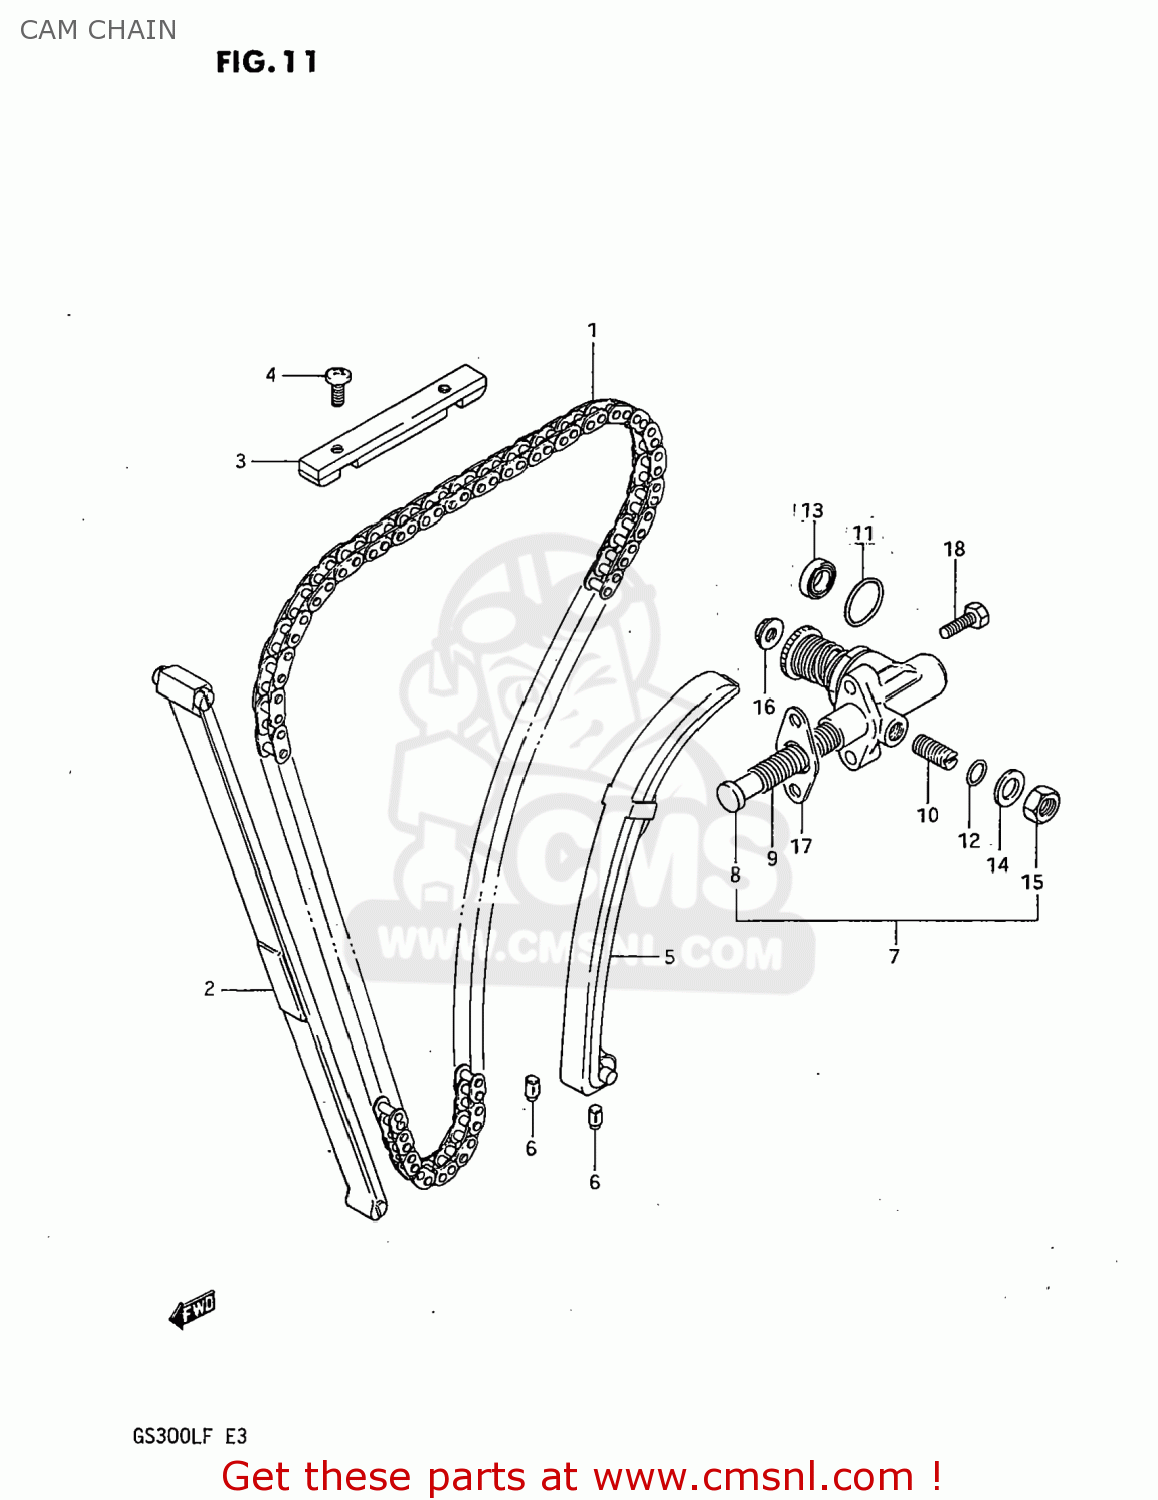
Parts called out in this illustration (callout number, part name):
1	CHAIN,CAMSHAFT DRIVE
2	GUIDE,CAM CHAIN NO.1
3	GUIDE,CAM CHAIN NO.3
4	SCREW
5	TENSIONER,CAM CHAIN
6	CUSHION,CAM CHAIN TENSIONER
7	ADJUSTER ASSEMBLY,TENSIONER
8	ROD,PUSH
9	SPRING
10	SCREW,TENSIONER ADJUST
11	O RING(D:2.4,ID:20.8)
12	O RING(D:1.9,ID:5.7)
13	SEAL,OIL(10X16X4)
14	WASHER
15	NUT
16	NUT 6MM
17	GASKET,TENSIONER ADJUSTER (MCA)
18	SCREW
